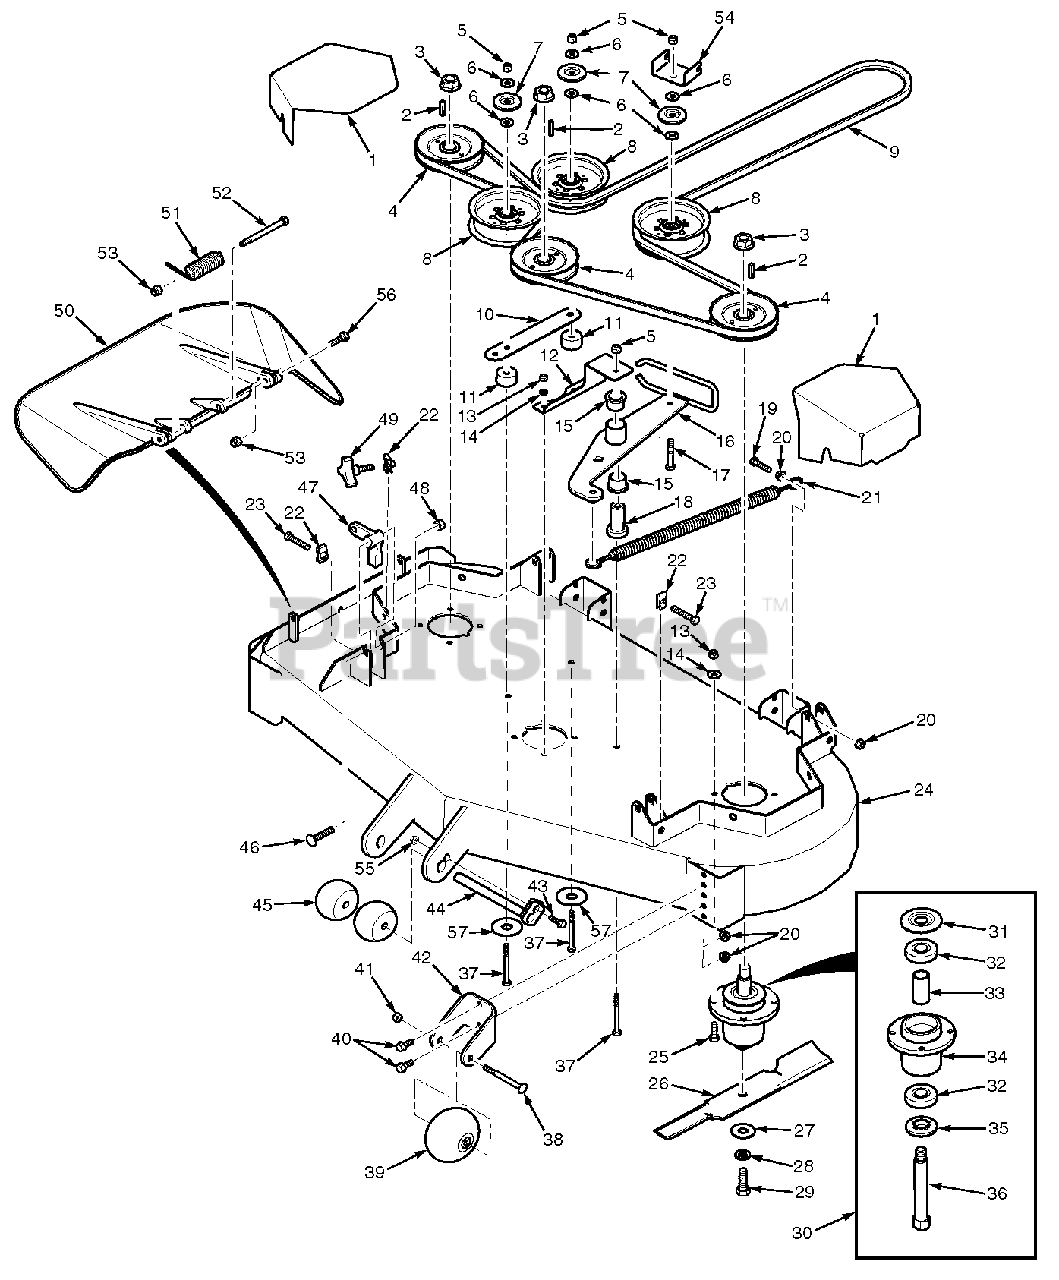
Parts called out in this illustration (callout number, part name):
1	Belt Cover
2	Key, 1/4 x 1/4 x 1-1/4"
3	Nut, 3/4-16 Spiral Lock
4	Pulley, 5.73" OD - 25mm Bore
5	Nut, Elastic Stop 3/8-16
6	Flatwasher, 3/8-.391 x .938 x .105
7	Dust Shield
8	Pulley, 5" Idler
9	Belt, Cutter Deck
10	Brace, Pulley
11	Spacer
12	Support, Idler Pivot
13	Nut, Elastic Stop
14	Lockwasher, 5/16 Spring
15	Bearing
16	Idler Arm (incl. item #15)
17	Bolt, Hex Head 3/8-16 x 2-1/2"
18	Pivot, Idler
19	Bolt, Hex Head 3/8-16 x 1-1/2 Gr.8
20	Nut, Serrated Flange 3/8-16
21	Spring, Idler
22	U-Nut, 3/8-16
23	Bolt, Hex Head 3/8-16 x 2"Special Lock
24	Cutter Deck w/Decals, SMTZ-52
25	Bolt, Hex Head 5/16-18 x 1-1/2"
26	Cutter Blade, 18"
27	Flatwasher, 5/8-.688 x 1.75 x .134 HD
28	Lockwasher, 1/2 Spring
29	Bolt, Hex Head 5/8-11 x 1-1/2"
30	Spindle Assembly
31	Debris Shield
32	Bearing
33	Spacer
34	Spindle Housing Assembly
35	(Incl. item #32, 33)
36	Protector, Bearing
37	Shaft, Spindle
38	Bolt, Hex Head 3/8-16 x 3-1/2"
39	Bolt, Carriage 3/8-16 x 4"
40	Wheel, Anti-Scalp
41	Bolt, Hex Head 3/8-16 x 1" Ser. Flg.
42	Nut, Center Lock 3/8-16
43	Bracket, Anti-Scalp
44	Bolt, Hex Head 5/16-18 x 1"
45	Shaft Weldment
46	Wheel, Anti-Scalp
47	Bolt, Carriage 7/16-14 x 2-1/4"
48	Lever, Deck Level
49	Nut, Elastic Stop 7/16-14
50	Knob w/Stud
51	Spring, Discharge Chute
52	Bolt, Hex Head 5/16-18 x 4-3/4"
53	Nut, Elastic Stop 5/16-18
54	Bracket, Belt Guide
55	Nut, Serrated Flange 5/16-18
56	Bolt, Hex Head 5/16-18 x 1-3/4"
57	Flatwasher, 3/8-.406 x 2.25 x .1875
